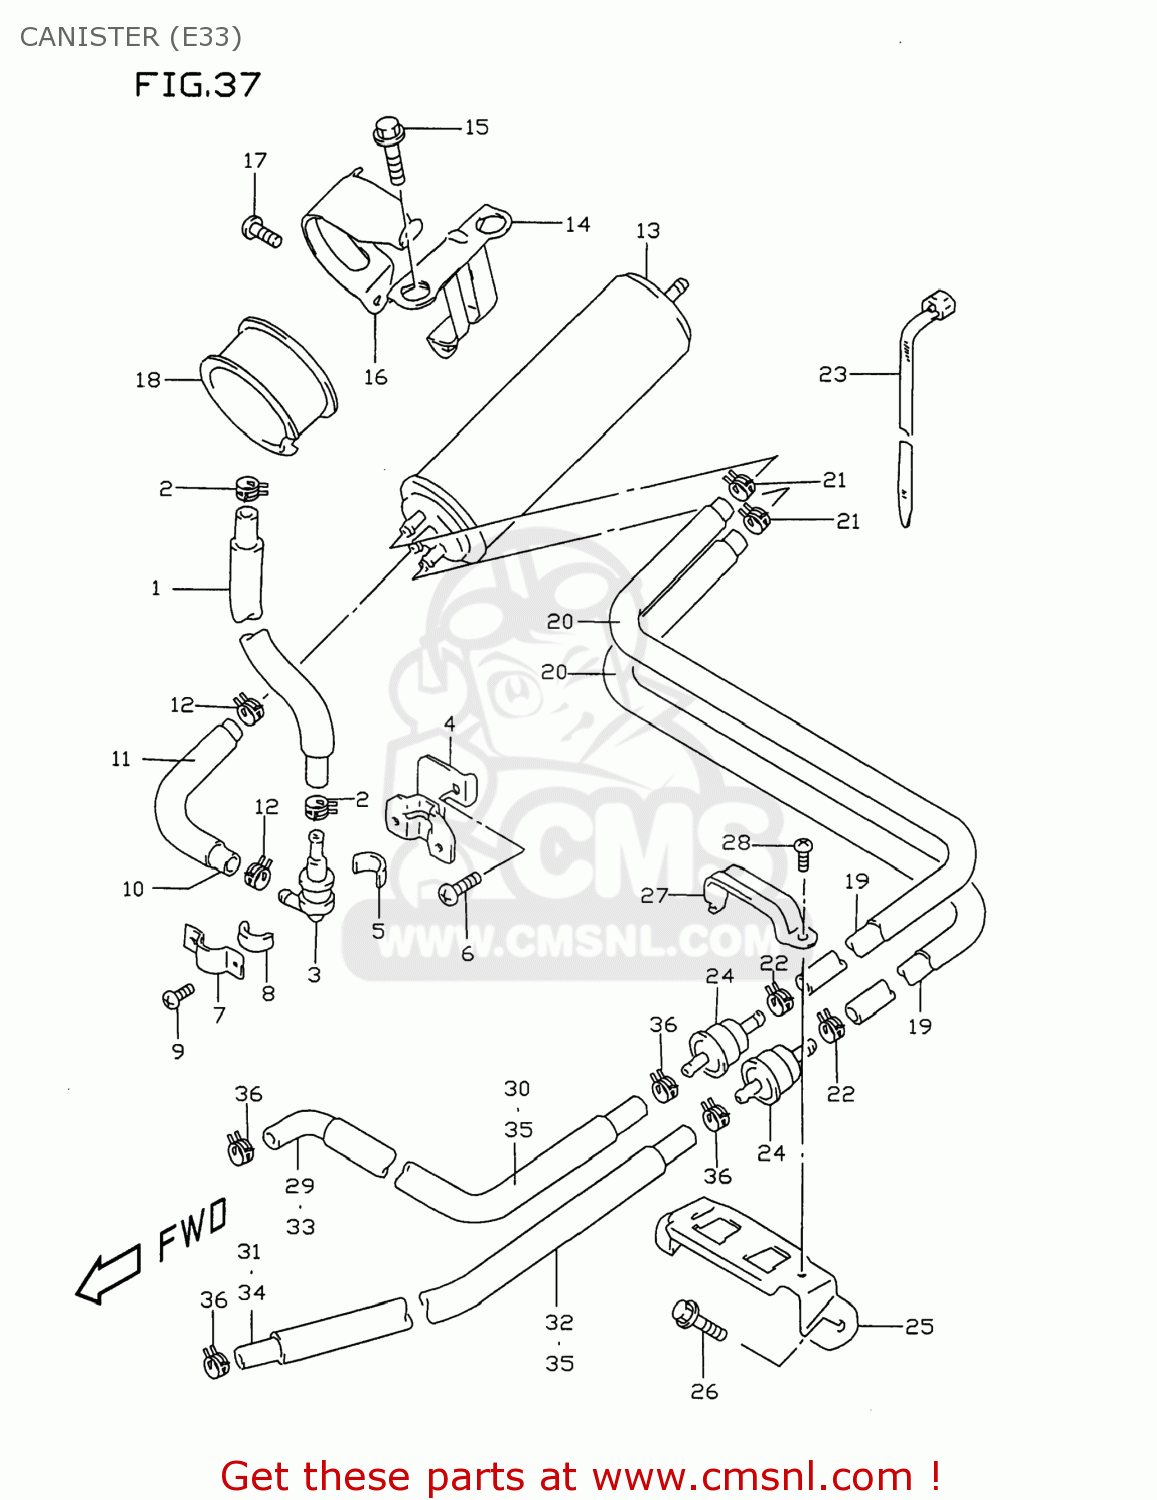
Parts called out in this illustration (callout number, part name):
1	HOSE(5.4X11.4X600)
2	CLIP
3	VALVE,FUEL TANK BREATHER
4	PLATE,BREATHER VALVE
5	CUSHION
6	SCREW 6X12
7	PLATE,FUEL TANK BREATHER NO.2
8	CUSHION
9	SCREW
10	HOSE(5.4X11.4X600)
11	PROTECTOR(14.5X15.5X600)
12	CLIP
13	CANISTER ASSY,CHARCOAL
14	BRACKET,CANISTER
15	BOLT(6X16)
16	HOLDER,CANISTER
17	SCREW 6X12
18	CUSHION,CANISTER
19	HOSE(5.4X11.4X600)
20	PROTECTOR(14.5X15.5X600)
21	CLIP
22	CLIP
23	CLAMP(L:165)
24	VALVE,CANISTER PURGE
25	BRACKET,CANISTER PURGE VALVE
26	BOLT
27	HOLDER,CANISTER PURGE
28	SCREW
29	HOSE(5.4X11.4X600)
30	PROTECTOR(14.5X15.5X600)
31	HOSE(5.4X11.4X600)
32	PROTECTOR(14.5X15.5X600)
33	HOSE(5.4X11.4X600)
34	HOSE(5.4X11.4X600)
35	SPRING
36	CLIP
